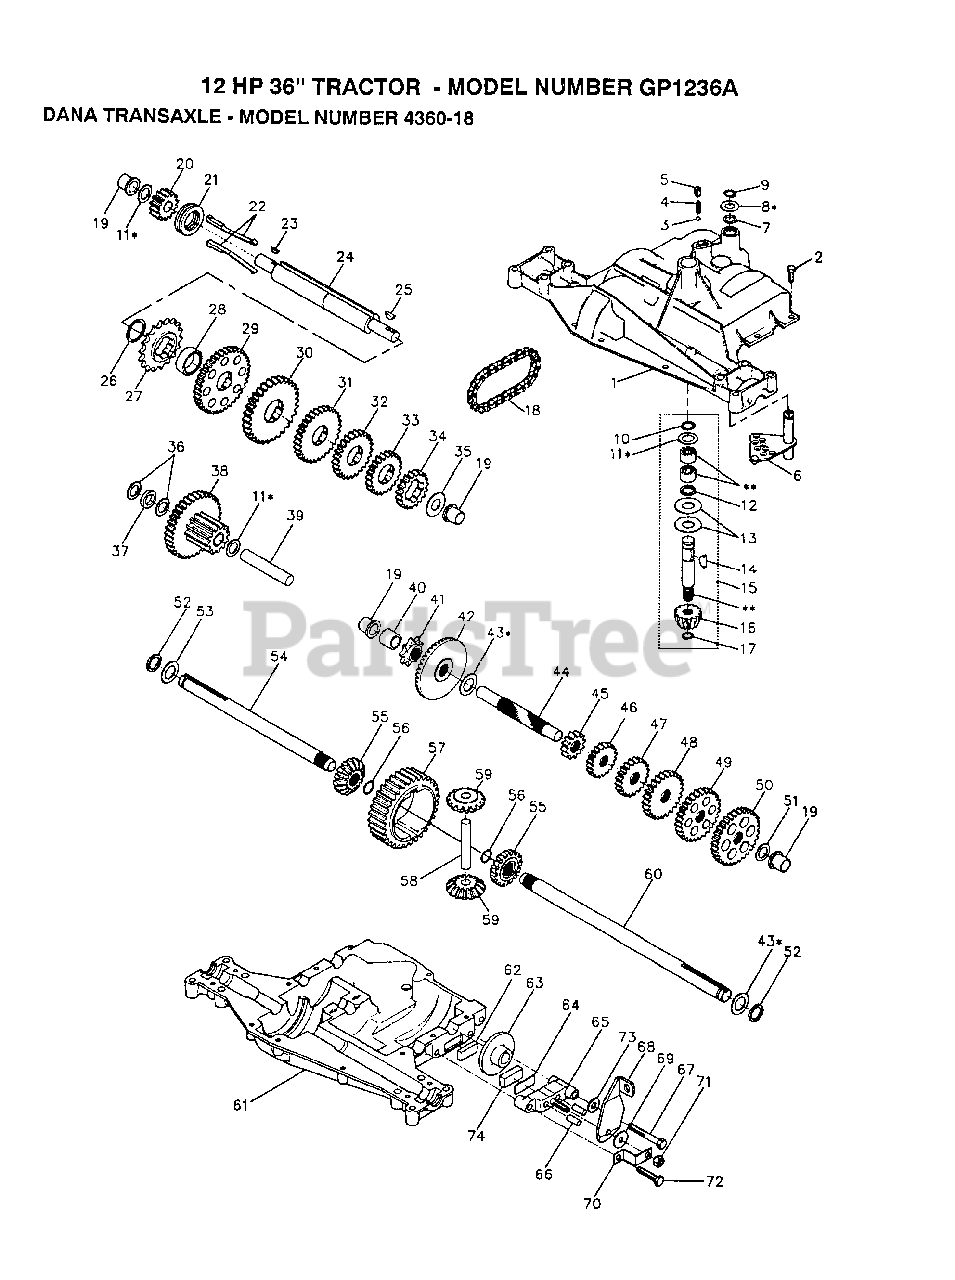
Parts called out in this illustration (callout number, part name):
1	HOUSING UPPER
3	BALL DETENT
4	SPRING, DETENT
5	SCREW, SET
6	ASSY SHIFTER
8	WASHER PLAIN
9	RING RETAINING
10	RING RETAINING
11	WASHER PLAIN
13	WASHER, PLAIN .632 X 1.38 X .046
14	KEY WOODRUFF #9
15	ASSY KIT INPUT SHAFT
16	PINION, BEVEL, 14 TEETH
17	RING, RETAINING
18	CHAIN, 24 PITCHES
19	BEARING, FLANGE
20	GEAR SPUR, 14 TEETH
21	COLLAR CLUTCH
22	KEY CLUTCH
23	KEY WOODRUFF #3
24	SHAFT INTERMEDIATE
25	KEY, WOODRUFF, #61
26	RING, RETAINING
27	SPROCKET, 18 TEETH
29	GEAR, SPUR, 37 TEETH
30	GEAR, SPUR, 35 TEETH
31	GEAR, SPUR, 30 TEETH
32	GEAR, SPUR, 25 TEETH
33	GEAR, SPUR, 22 TEETH
35	WASHER, PLAIN .640 X 1.37 X .061
36	WASHER, PLAIN .632 X 1.00 X .026
37	SPACER .630 X 1.00 X .169
38	ASSY GEAR COMB 12&35 TEETH
39	SHAFT IDLER
40	SPACER .635 X .875 X .755
41	SPROCKET, 9 TEETH
42	GEAR, BEVEL, 42 TEETH
43	WASHER PLAIN
44	SHAFT, DRIVE
45	GEAR, SPUR, 12 TEETH
46	GEAR SPUR, 15 TEETH
47	GEAR, SPUR, 20 TEETH
48	GEAR, SPUR, 25 TEETH
49	GEAR, SPUR, 28 TEETH
50	GEAR, SPUR, 31 TEETH
51	WASHER, PLAIN .632 X 1.00 X .060
53	WASHER PLAIN
54	AXLE LEFT HAND
55	GEAR, MITER, 15 TEETH
56	RING, RETAINING
57	GEAR, SPUR, 32 TEETH
58	SHAFT, CROSS
59	GEAR, MITER, 15 TEETH
60	AXLE RIGHT HAND
61	HOUSING LOWER
62	PUCK, FRICTION
63	DISC, BRAKE
65	JAW, BRAKE
66	PIN, DOWEL
67	SCREW TAPPING
68	LEVER, ACTUATING
69	WASHER, PLAIN .321 X 1.00 X .055
70	BRACKET, ANTI-ROTATION
71	LOCKNUT 5/16-24
72	SCREW TAPPING
73	WASHER PLAIN
74	PUCK, FRICTION
